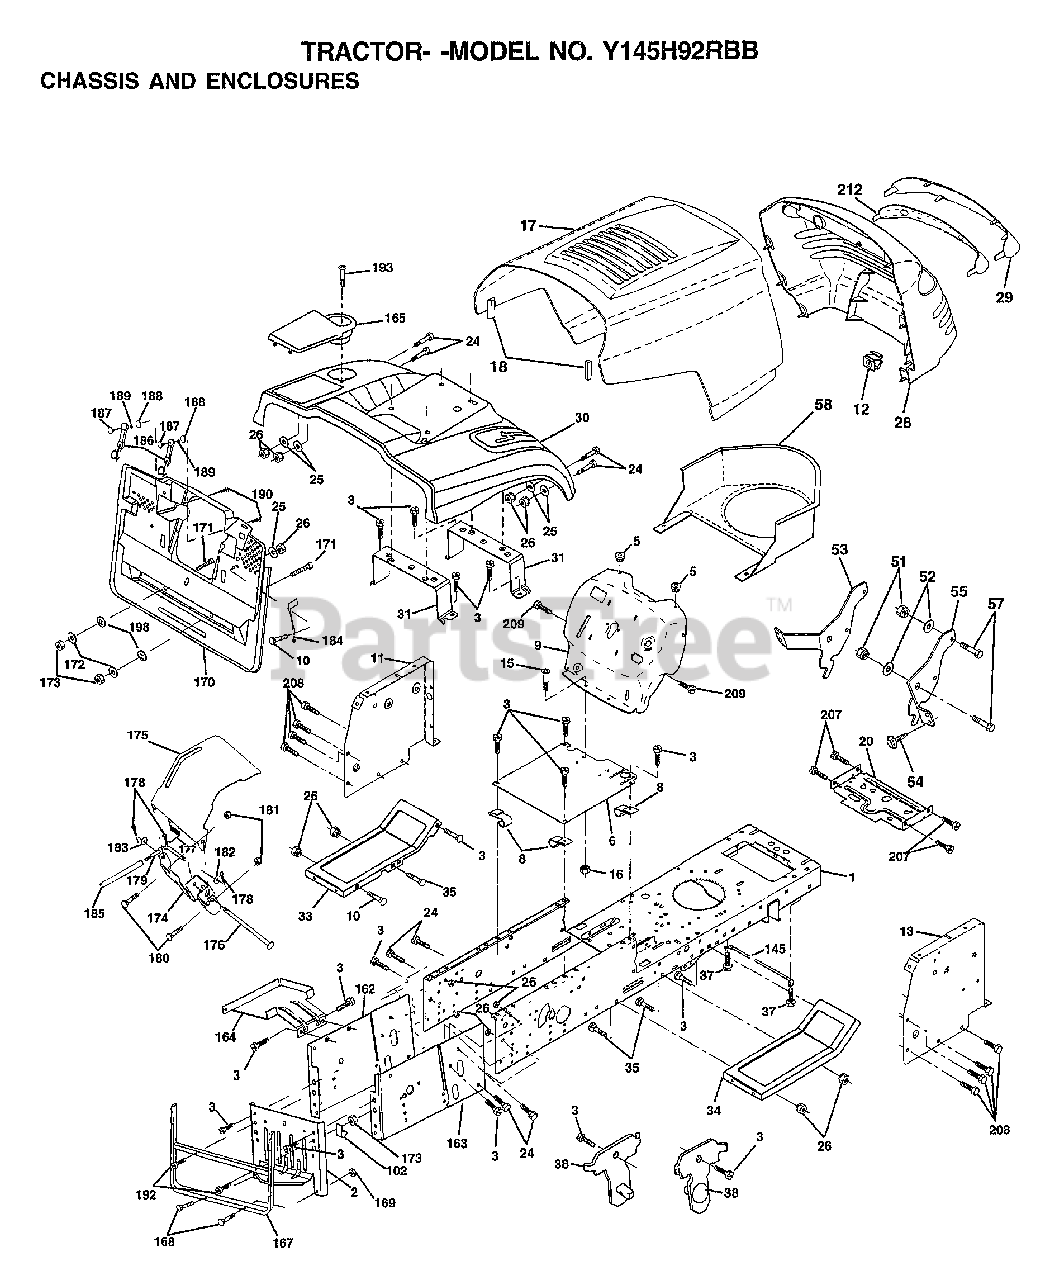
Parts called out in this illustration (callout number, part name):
2	DRAWBAR.CRD
3	SCREW
5	BUMPER-HOOD/DASH
6	SADDLE
8	"CLIP,INSULATOR"
9	DASH
11	"PANEL-DASH,LH"
12	CLIP.TINNERMAN
15	SCREW
17	HOOD.STEEL.ASSY
20	"PLATE-MTG,BATT/FU"
24	BOLT
25	WASHER
26	NUT
28	GRILL.BLK
29	LENS.GRILLE.PRIVATE LABEL
31	BRKT.SUPT.FENDER.CRD
33	FOOTREST.LH.LT/GT
34	FOOTREST.RH.LT/GT
35	BOLT
37	SCREW LT
38	BRKT ASM PIVOT MOWER REAR
51	NUT
52	WASHER
53	BRACKET.GRILLE.LH
54	SCREW.HEX.WS.HD
55	BRACKET.GRILLE.RH
58	AIR DUCT
102	CLIP T
145	"ROD POVOT,CHASSIS"
162	BRKT.EXT.CHASSIS.LH.CRD
163	BRKT.EXT.CHASSIS.RH.CRD
164	SUPPORT.BATTERY.CRD
165	COVER.BATTERY.CRD.BLACK.LT
167	SUPT.ASM.BACKPLATE
168	BOLT-RD HD SQ NK
170	COVER.BACKPLATE.BLACK
171	BOLT.HEX.3/8-16X2-1/2
173	NUT
174	BRKT.SWITCH.FBI.CRD
175	GRUARD.DOOR.REAR.CRD
176	HINGE PIN
177	SPRING.COVER.LH
179	ROD.PIVOT.FBI.CRD
182	WASHER.385X.625
183	WASHER
184	BRKT.ACTUATOR.BAG.CRD
185	TUBE.LEVER.SWCH.FBI.CRD
186	LATCH ASSY.BAGGER
187	WELDNUT
188	WASHER #10
189	LOCKWASHER
190	SCREW
192	SCREW LT
193	SCREW
198	NUT PUSH
207	SCREW
208	SCREW
209	SCREW
212	INSERT LENS REFLECT
